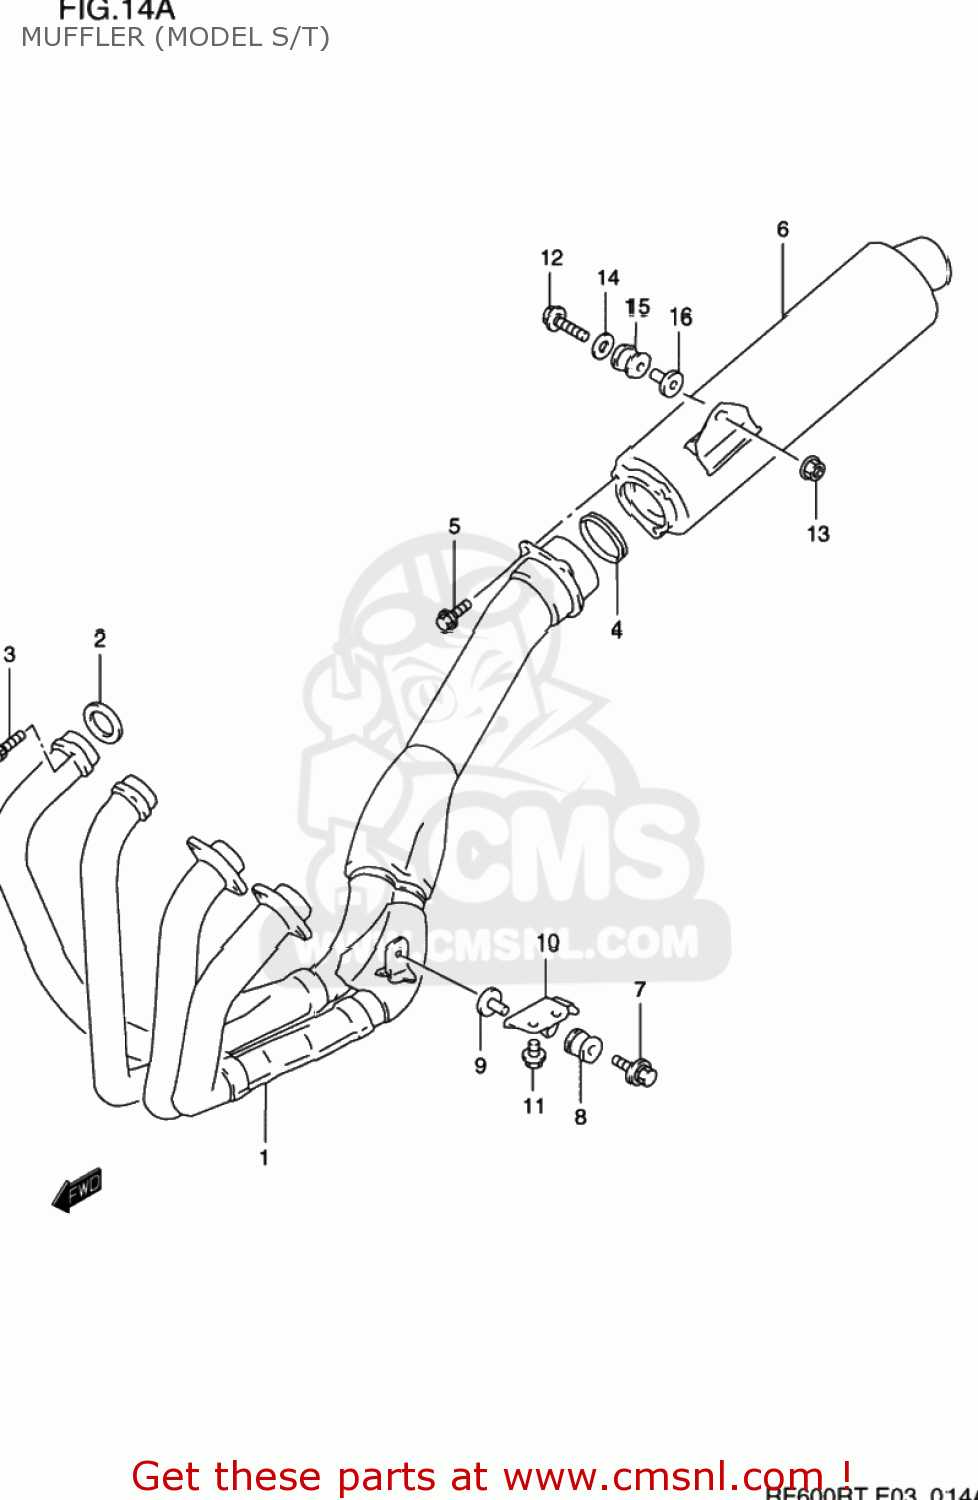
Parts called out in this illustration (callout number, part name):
1	EXHAUST
2	GASKET,EXHAUST PIPE
3	BOLT
4	GASKET,MUFFLER JOINT
5	BOLT(8X20)
6	BODY,MUFFLER
7	BOLT 8X45
8	CUSHION
9	SPACER(8.6X12X24.2)
10	BRACKET,MUFFLER SUPPORT FR
11	BOLT
12	BOLT
13	NUT
14	WASHER (8.1X33X1.6)
15	CUSHION
16	SPACER(8.6X12X27.1)
